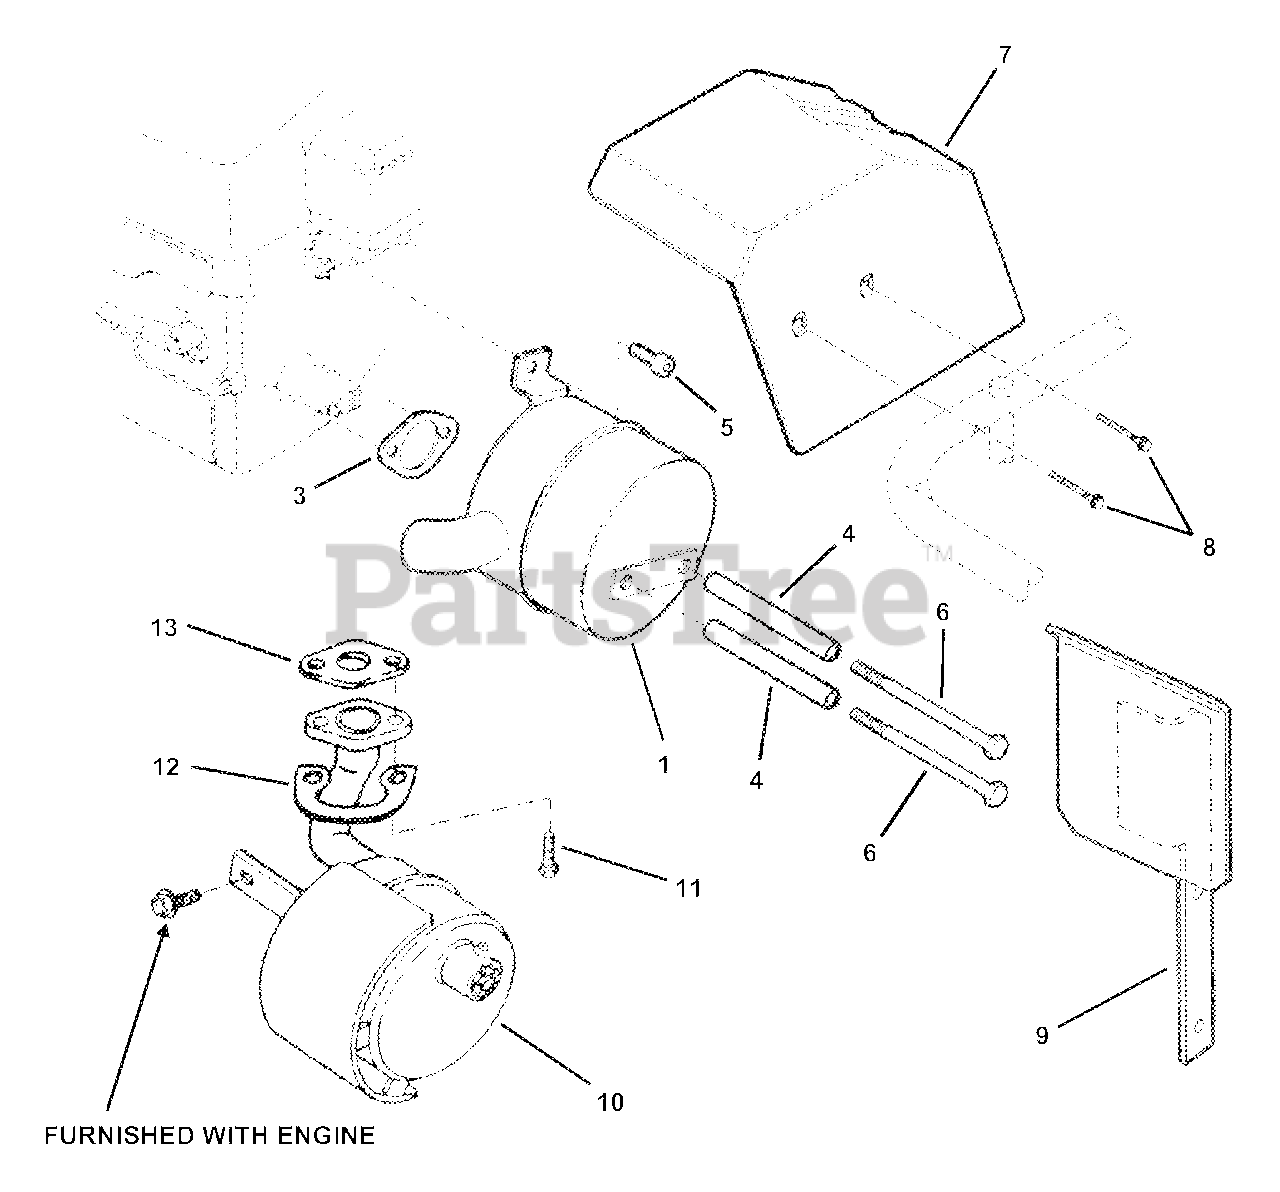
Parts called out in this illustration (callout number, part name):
1	MUFFLER, 12HP Tecumseh
3	GASKET, Exhaust
4	SPACER, .312 I.D. x 3-1/2"
5	SCREW, 1/4-20 x 1/2" Socket Head Cap
6	SCREW, 5/16-18 x 4-1/4" Hex Head Cap
7	ASSEMBLY, Heat Shield
8	SCREW, #10-32 x 1-1/2" Hex Washer Head
9	HEAT SHIELD
10	MUFFLER, 16HP Tecumseh
11	SCREW, 5/16-18 x 1" Hex Head Cap, Grade 5
12	PLATE, Lock
13	GASKET, Exhaust
